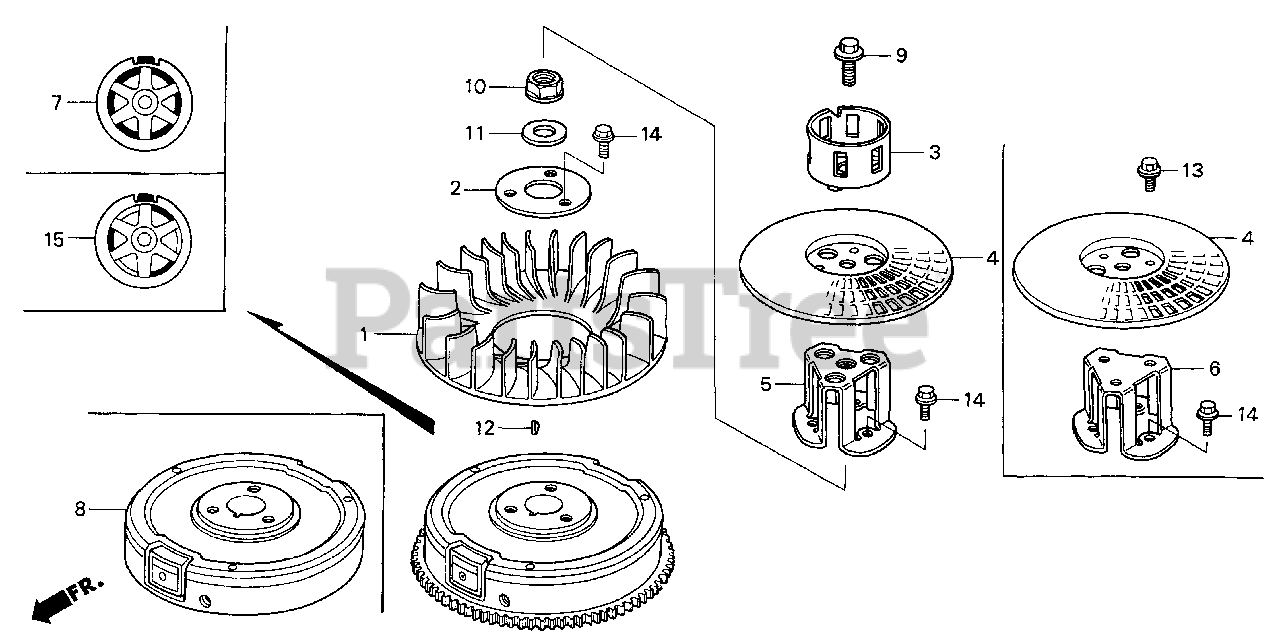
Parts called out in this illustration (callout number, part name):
1	FAN, COOLING
2	PLATE, COOLING FAN SETTING
7	FLYWHEEL
10	NUT, FLANGE (20MM)
11	WASHER (20MM)
12	KEY, SPECIAL WOODRUFF (25X18)
14	BOLT, FLANGE (8X16)
